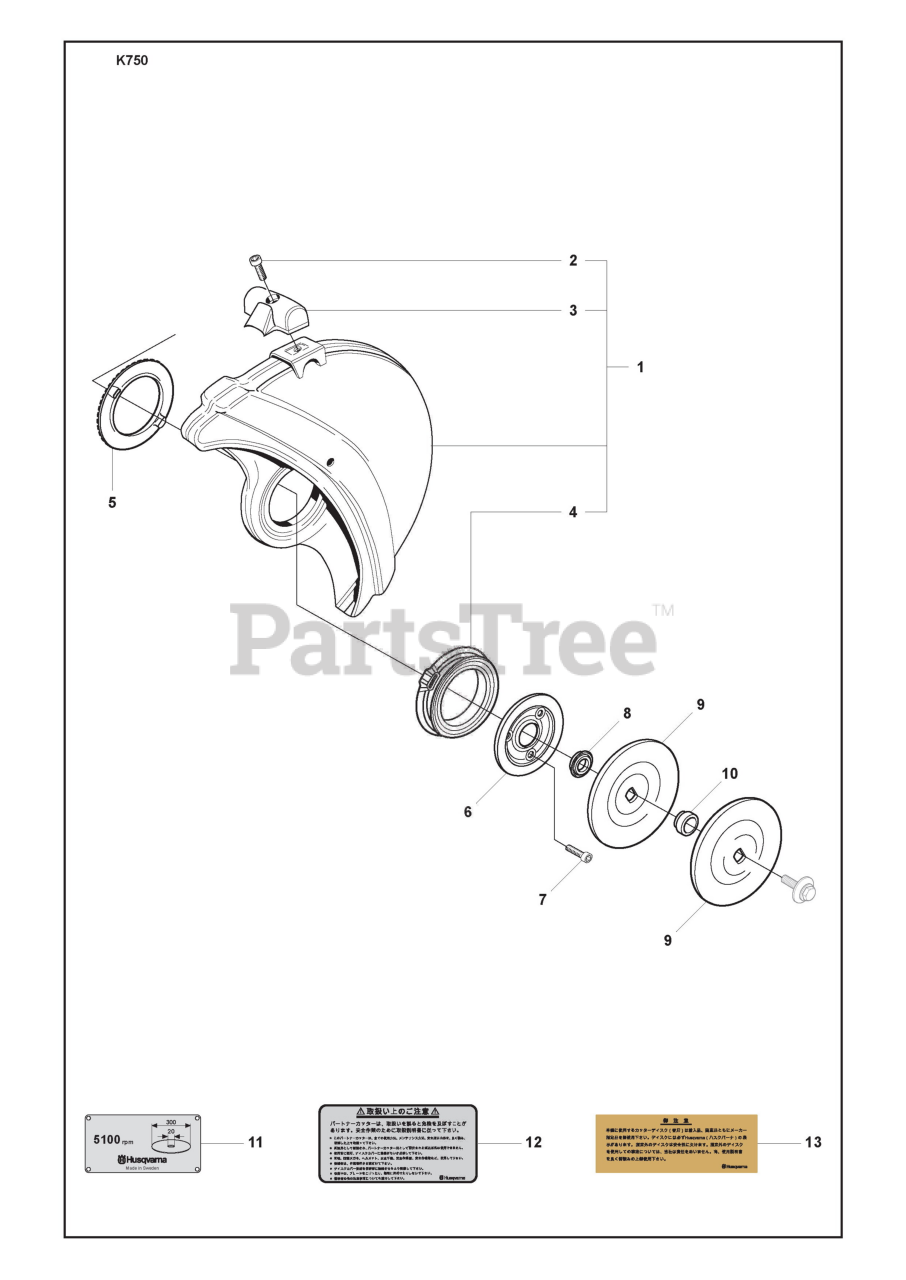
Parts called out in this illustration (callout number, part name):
1	WHEEL GUARD ASSY
2	SCREW
5	SCREEN PATTERN FLANG
8	SUPPORT FLANGE
9	FLANGE WASHER
10	BUSHING
11	LABEL
12	LABEL
13	LABEL
